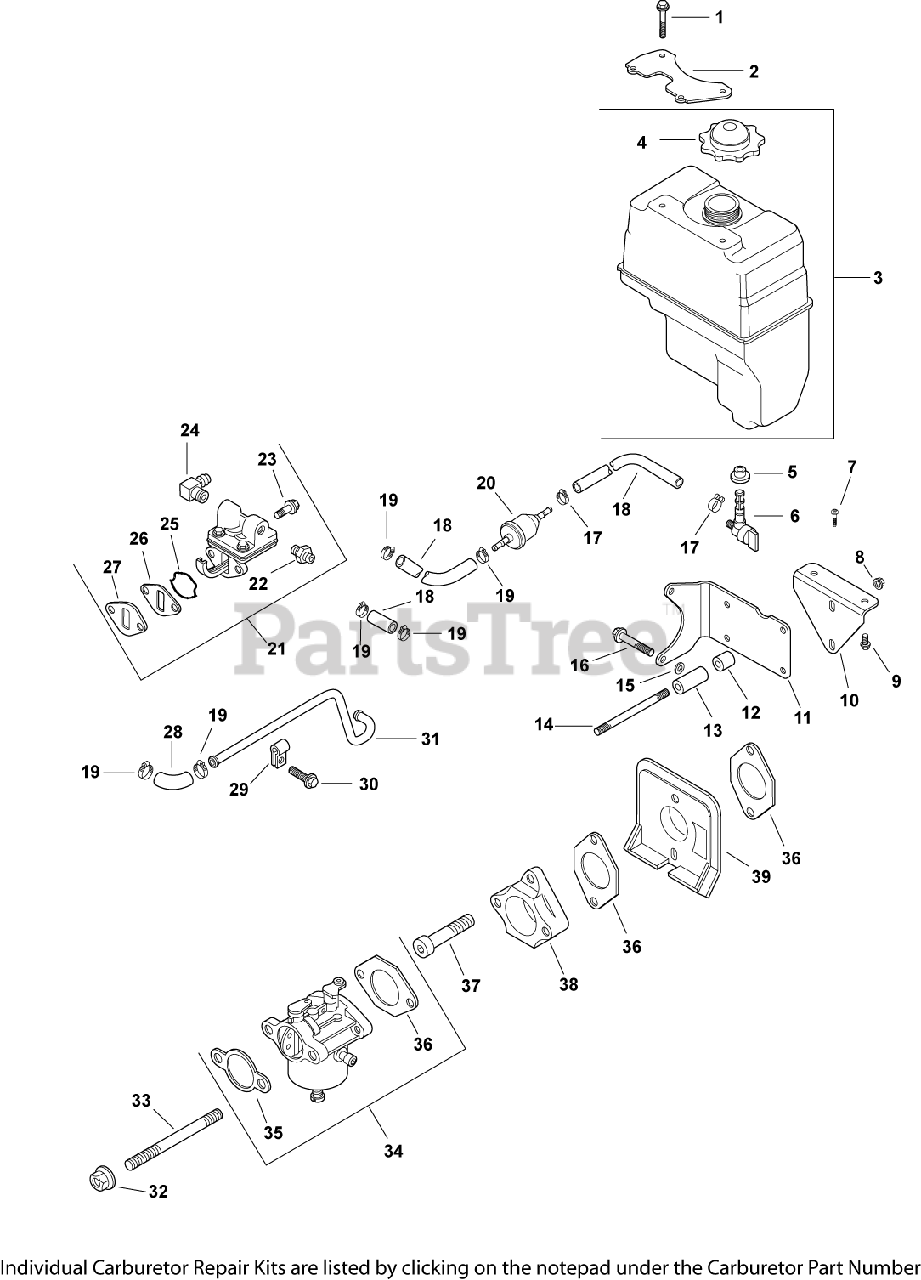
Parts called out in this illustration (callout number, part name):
1	SCREW,FLG THD FRM M6X1.0X25-(#25086395S)
2	BRACKET, FUEL TANK
3	KIT, FUEL TANK
4	CAP, FUEL TANK
5	BUSHING, FUEL TANK
6	VALVE, FUEL SHUT-OFF
7	SCREW, LBD SKT M6x1.0x20-(#25086403S)
8	NUT, FLG M8X1.25
9	SCREW, FLG M6X1.0X12
11	BRACKET, FUEL TANK
14	STUD, M8X1.25X133-USE 25 755 54-S
15	WASHER, FLAT 11/32"
16	SCREW, FLG M8X1.25X50
17	CLAMP, BAND SPRING HOSE-(#2523737S)
18	HOSE,LW PERM.FUEL 24.00"-USE 25 111 81-S
19	CLAMP, HOSE (KM)-USE 25 237 31-S
20	FILTER,FUEL 51 MICRON (FUEL PUMP)
21	KIT, FUEL PUMP
22	KIT, STRAIGHT FITTING
23	SCREW,FLG THD FRM M6X1.0X20-(#25086396S)
24	CONNECTOR, 90 DEG. HOSE
25	O-RING, FUEL PUMP
26	SPACER, FUEL PUMP
27	GASKET, FUEL PUMP
28	HOSE, FUEL LOW-PERMEATION
30	SCREW, FLG THD FRM M5X.8X10
31	LINE, FUEL - DISCONTINUED
32	NUT, FLG M6X1.0
33	STUD,M6X1.0X116
34	KIT, CARBURETOR - USE 12 853 178-S
35	GASKET, AIR CLEANER BASE
36	GASKET, CARBURETOR
37	SCREW, SKT CAP M6X1.0X35
38	ADAPTER, CARBURETOR
39	DEFLECTOR, HEAT
